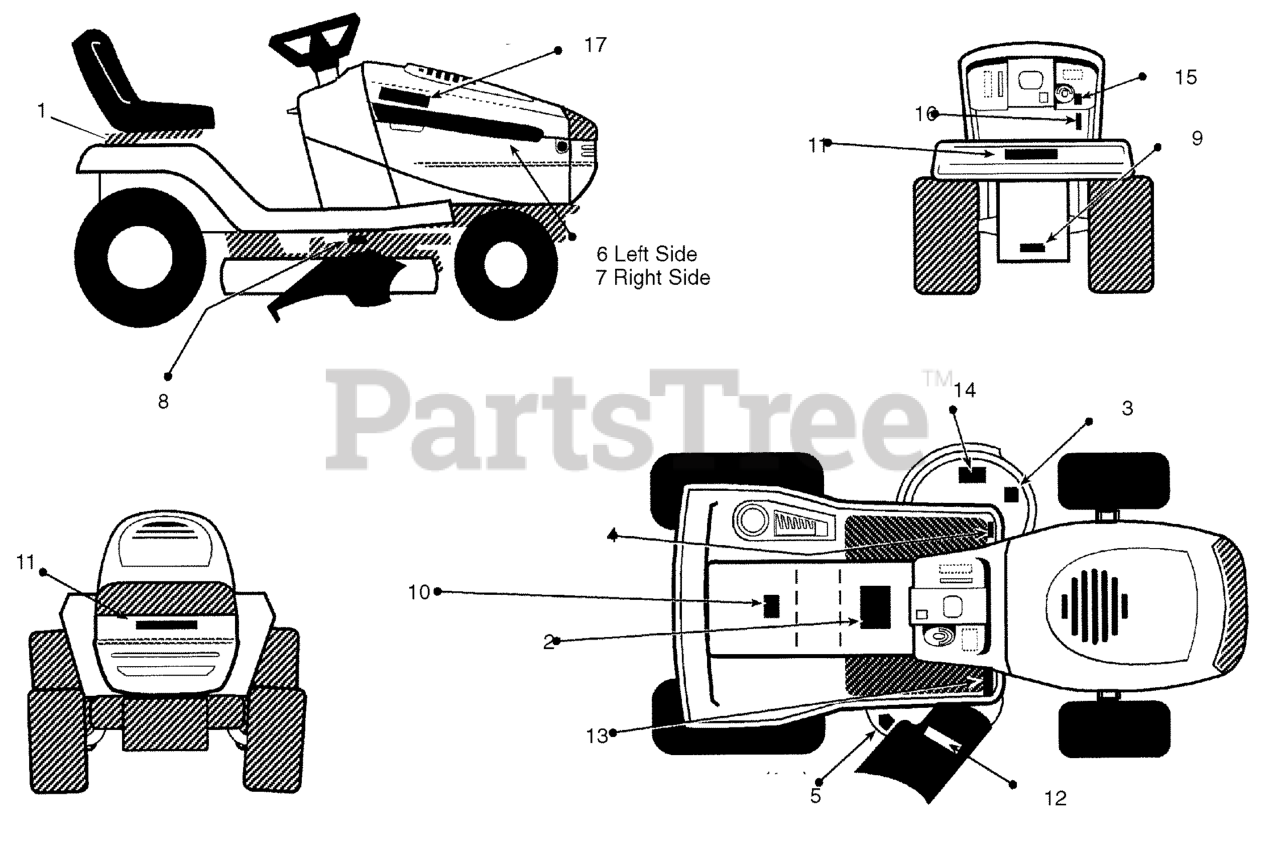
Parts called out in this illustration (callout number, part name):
1	DEKA (Battery)
2	Warning (Console - Center)
3	NO STEP (Mower Deck - Left Side)
4	Park / Brake
5	Cut Finger (Mower Deck -Right Side)
6	22/46 Auto Twin - Left Side
7	22/46 Auto Twin - Right Side
8	Gage Wheel Level
9	Warning Load Limit (Rear)
10	Auto Disconnect
11	Craftsman Logo
12	Mulch Kit Installed
13	Hydro Drive
15	Deck Height
16	Up / Down
17	Craftsman Nameplate
